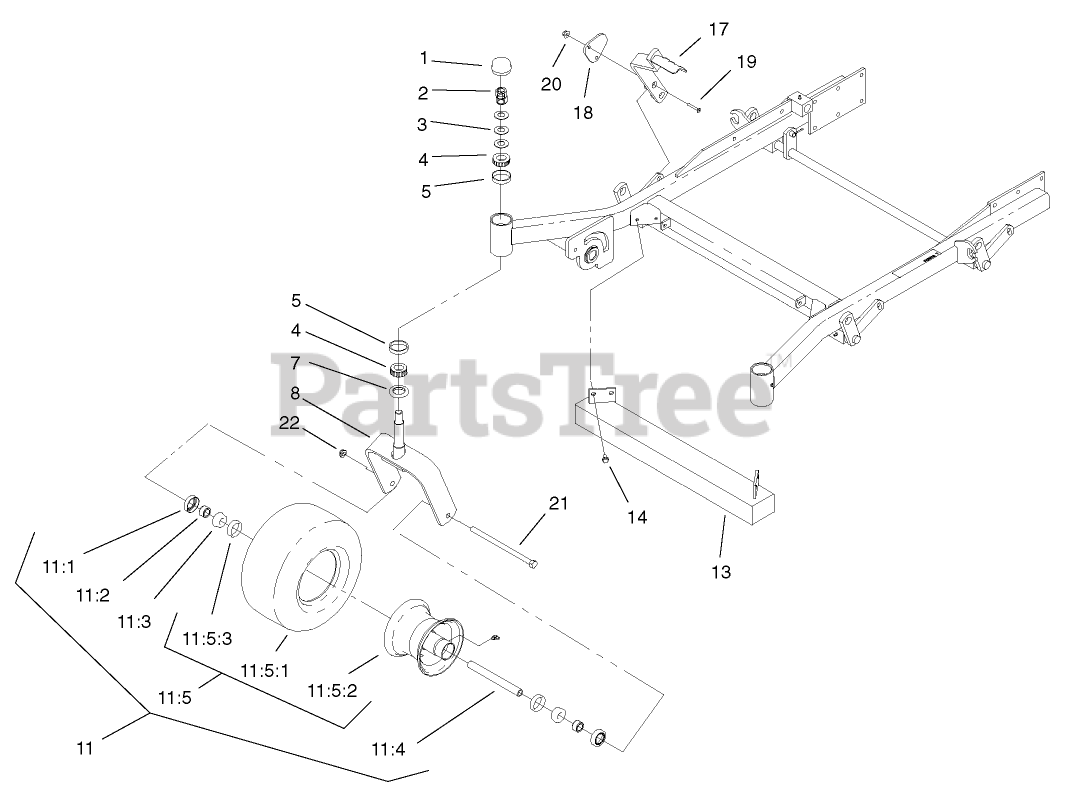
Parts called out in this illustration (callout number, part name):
1	CAP-GREASE
2	NUT-LOCK, NI
3	WASHER-BELLVILLE
4	BEARING-CONE, TAPERED
5	BEARING-CUP, TAPERED
7	SEAL-GREASE
8	CASTER-FORK
11	CASTER WHEEL ASM
11:1	SEAL-BEARING
11:2	SPACER-BEARING
11:3	BEARING-CONE, TAPER
11:4	SPACER-CASTER, FRONT
11:5	WHEEL AND TIRE ASM
11:5:3	BEARING-CUP
13	Weight ASM
14	SCREW-HWHTF
17	LEVER-LIFT, DECK
19	SCREW
20	NUT-HF
21	Screw-HH
22	NUT-LOCK, NI
